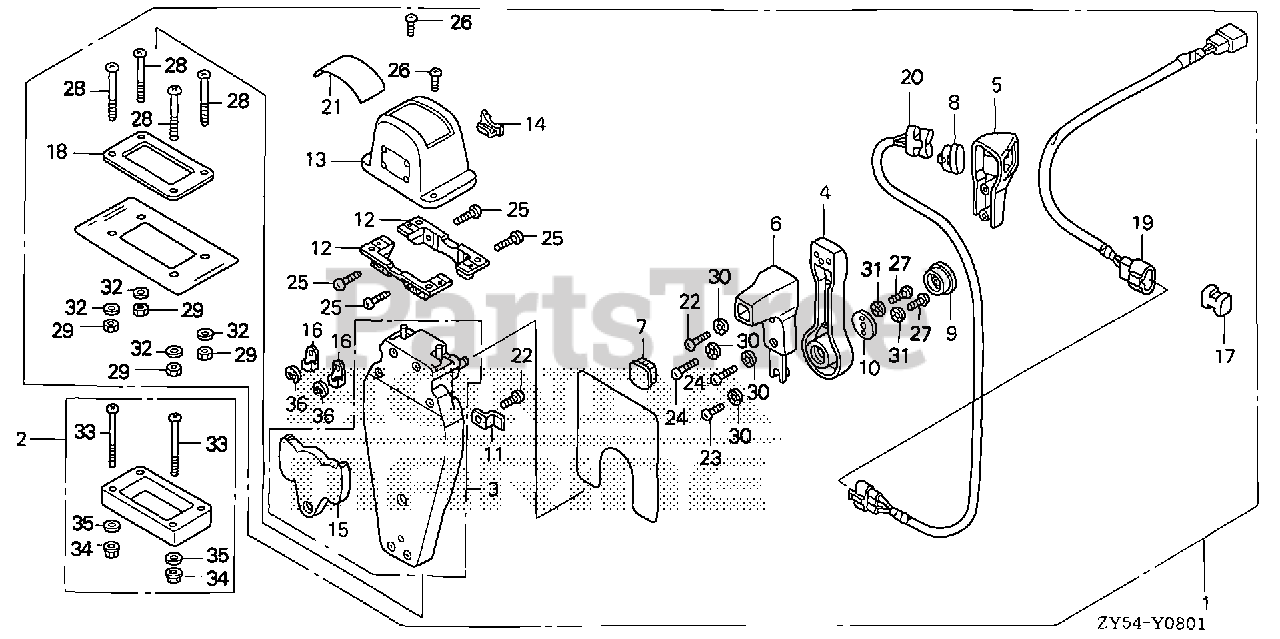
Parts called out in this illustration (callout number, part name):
1	BOX KIT, REMOTE CONTROL (TOP MOUNT SINGLE)(L)
2	SPACER KIT, REMOTE CONTROL BOX (TOP MOUNT SINGLE)
3	HOUSING ASSY., R. (INNER) (TOP MOUNT)
4	HANDLE, REMOTE CONTROL
5	COVER, R. GRIP
6	GRIP, REMOTE CONTROL HANDLE
7	CAP, GRIP
8	CAP, SWITCH
9	BUTTON, THROTTLE
10	PLATE, HANDLE
11	PLATE, CABLE CLAMP
12	BRACKET, REMOTE CONTROL HOUSING
13	HOUSING, REMOTE CONTROL BOX
14	HOUSING, LEAD
15	PLATE, DWELL
16	TERMINAL, CABLE
17	SPACER, CABLE CLAMP
18	GASKET, SINGLE
19	SUB-HARNESS ASSY., POWER TRIM-TILT (B)
20	SWITCH ASSY., POWER TRIM-TILT (B)
21	MARK, REMOTE CONTROL (SINGLE)
22	SCREW, PAN (5X16)
23	SCREW, PAN (5X10)
24	SCREW, PAN (5X20)
25	SCREW, PAN (5X18)
26	SCREW, PAN (4X10)
27	SCREW, PAN (6X18)
28	SCREW, PAN (5X40)
29	NUT, HEX. (5MM)
30	WASHER, LOCK (5MM)
31	WASHER, LOCK (6MM)
32	WASHER, PLAIN (5MM)
33	SCREW, PAN (5X65)
34	NUT, HEX. (5MM)
35	WASHER, PLAIN (5MM)
36	E-RING (6MM)
